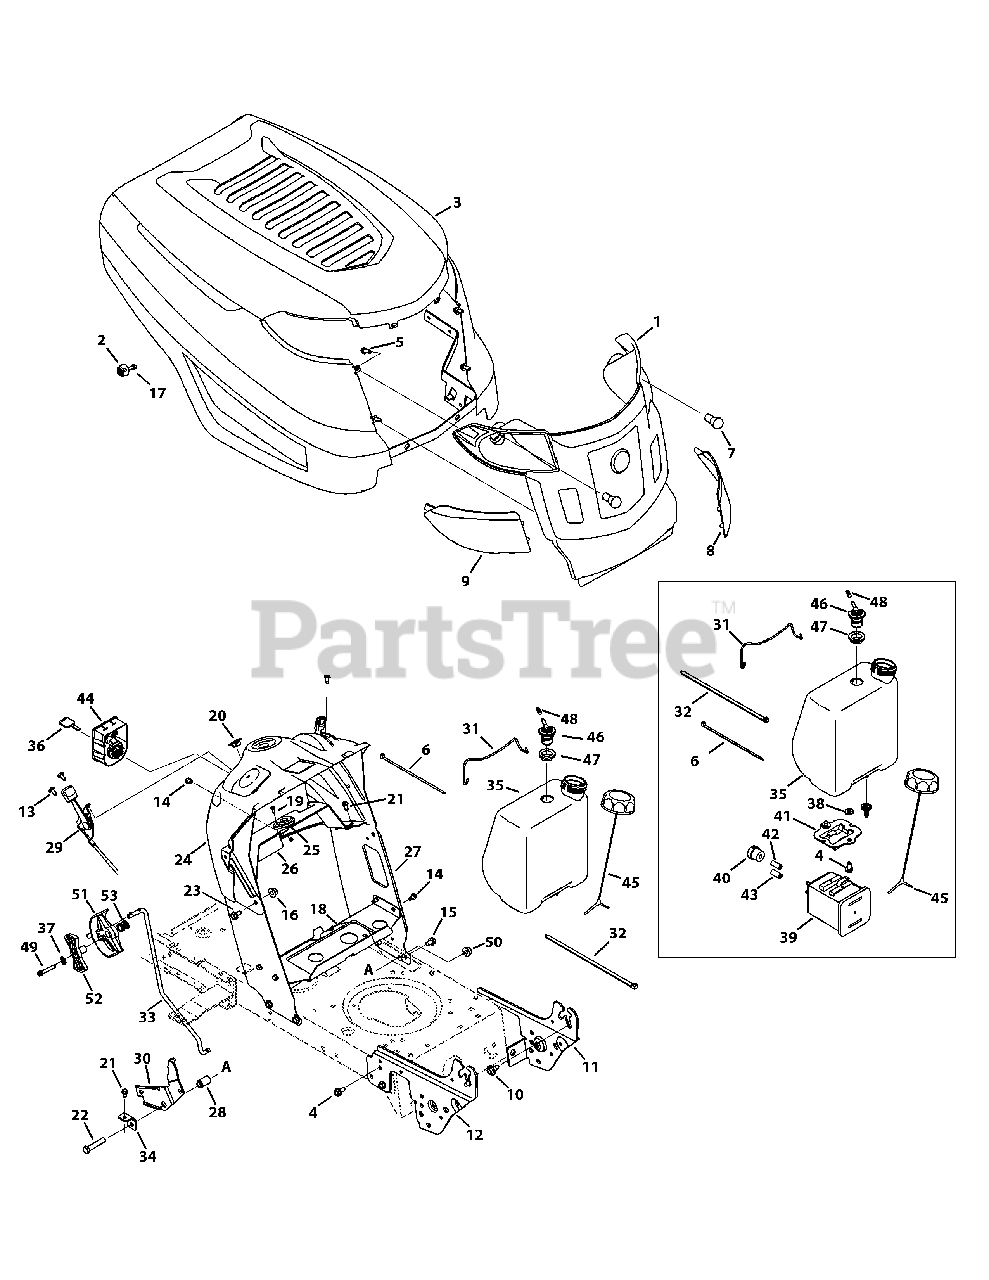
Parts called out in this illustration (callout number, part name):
1	Grill Assembly, Troy-Bilt
2	K-Style Bumper
4	Screw, 5/16-18 x .750
5	Screw, 1/4-15 x .750
6	Cable Tie
9	Right Lens
10	Shoulder Screw, 5/16-18 x .43 x .29
11	Left Support Pivot Bracket
12	Right Support Pivot Bracket
13	Screw, 1/4-20 x .500
14	Screw, 1/4-20 x .500
15	Screw, 5/16-18 x .625
16	Flangelock Nut, 5/16-18
17	Screw, #12-16 x 1.25
18	Gas Tank Support Bracket
19	Screw, #10-16 x .500
20	Choke Plug
21	Tap Screw, 1/4-20, 0.625
22	Hex Screw, 3/8-16 x 2.0
23	Hex Screw, 5/16-18 x .625
24	Dash, Upper
25	Bearing, .628 ID x 1.36
26	Bracket, Steering Support
27	Dash, Lower
28	Flange Spacer, .390 x .671 x 1.095
29	Throttle/Choke Cable
31	Battery Assembly Rod
32	Cable Tie
33	Speed Control Rod
34	Speed Latch Tab
35	1.36 Gallon Fuel Tank
37	Lock Washerer, 1/4
38	Flat Washerer, .344 x .750 x .120
39	5 Gallon Carbon Canister
40	Vent Filter Canister
41	Canister Adapter Bracket
42	Fuel Hose, White
43	Fuel Hose, Yellow
44	Switch, 3 Position Key
45	Fuel Cap, 2.25" Vented w/Tether
45	Fuel Cap, 2.25" EPA, w/Retainer
46	Rollover Valve
47	Rubber Grommet, 23 x 3.55
48	Hose Vent, 3/16 EPA
49	Hex Washerer Screw, 1/4-20 x 1.50
50	Flangelock Nut, 3/8-16
51	Shift Lever
52	Index Control
53	Compression Spring, .72 OD x .78
